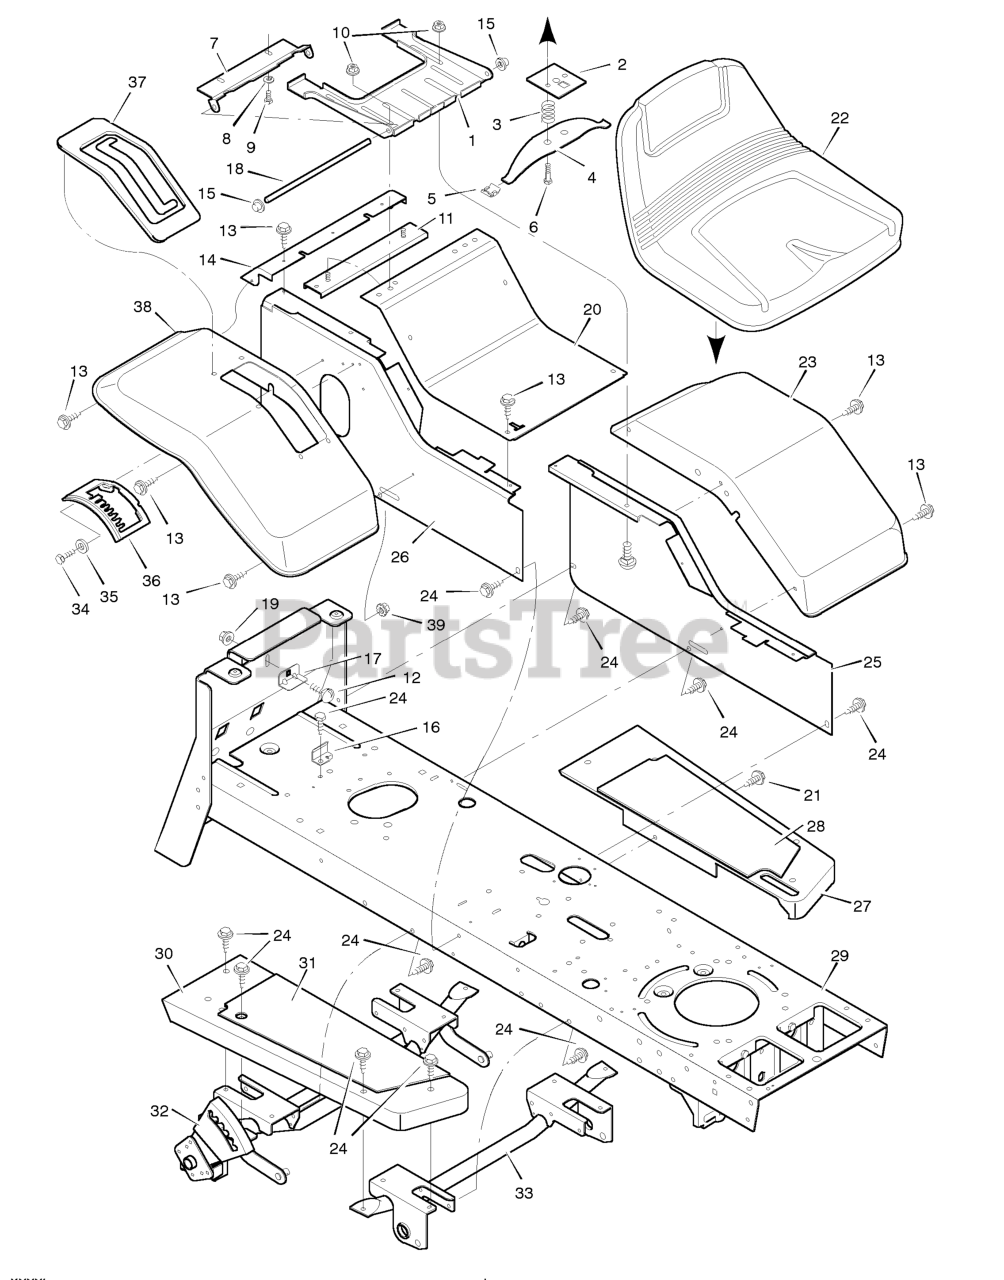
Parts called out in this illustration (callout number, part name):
1	Bracket, Seat
2	Plate Assembly, Switch
3	Spring, Compression
4	Spring, Seat
5	Glide, Spring
6	Bolt, Shoulder
7	Support, Seat
8	Lockwasher
9	Bolt, Hex
10	Locknut, Flange
11	Channel Assembly
12	Bolt, Carriage
14	Insert, Rear
15	Push On Cap
16	Clip, Battery
17	Clamp, Battery
18	Rod, Pivot
19	Locknut
20	Panel, Top
21	Fastener, Panel
25	Panel, Left
26	Panel, Right
27	Running Board, Left
28	Mat, Left
29	Frame Channel
30	Running Board, Right
31	Mat, Right
32	Lifter and Support Assembly
33	Support Assembly, Front
36	Gate, Shift
37	Cover, Shift
38	Fender, Right
39	Locknut
